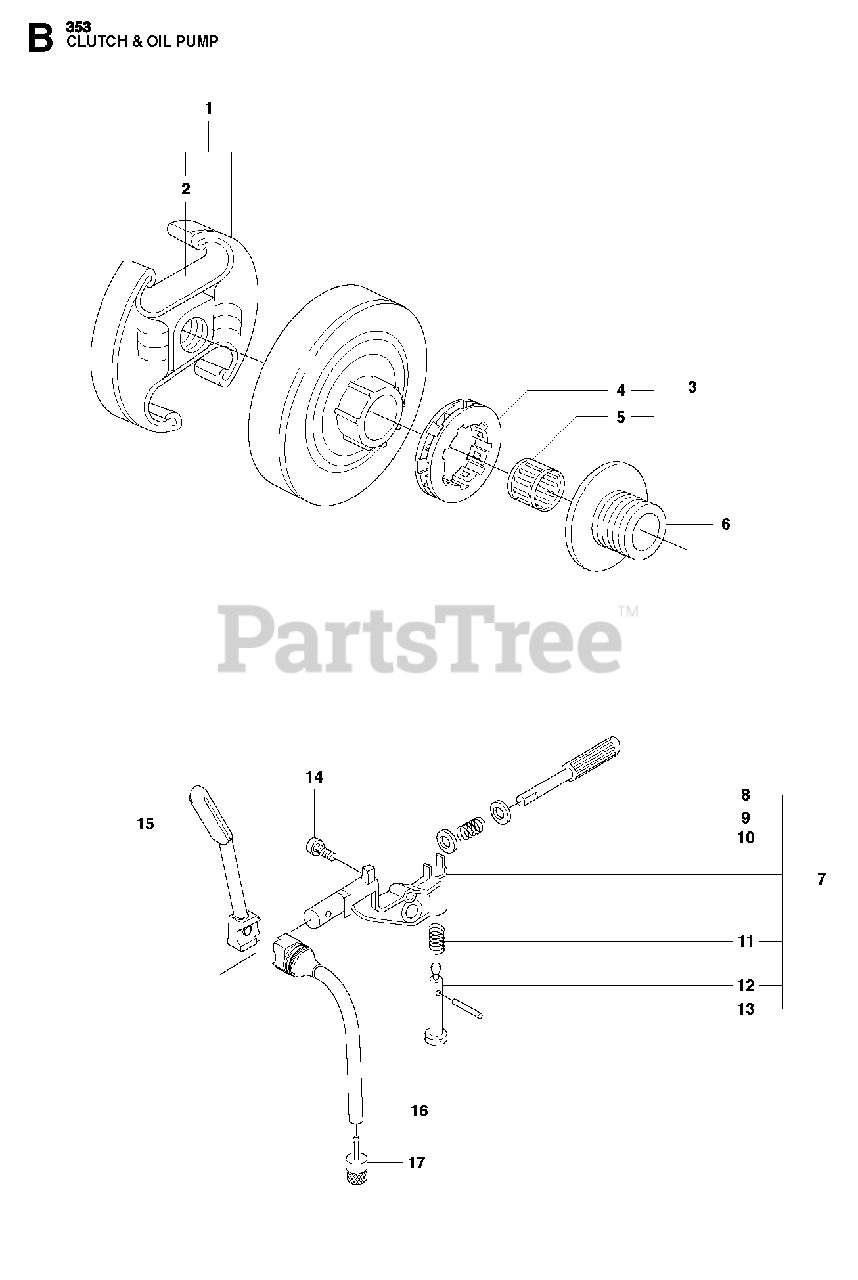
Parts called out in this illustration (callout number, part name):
2	SPRING
3	CLUTCH DRUM
4	RIM SPROCKET 7T .325
5	NEEDLE BEARING
6	PUMP PINION
7	OIL PUMP ASSY
8	PUMP PISTON
9	WASHER
10	SPRING
11	SPRING
12	ADJUSTER
13	PIN
15	OIL PRESSURE HOSE
16	RP HOSE
17	OIL PLUMMET
